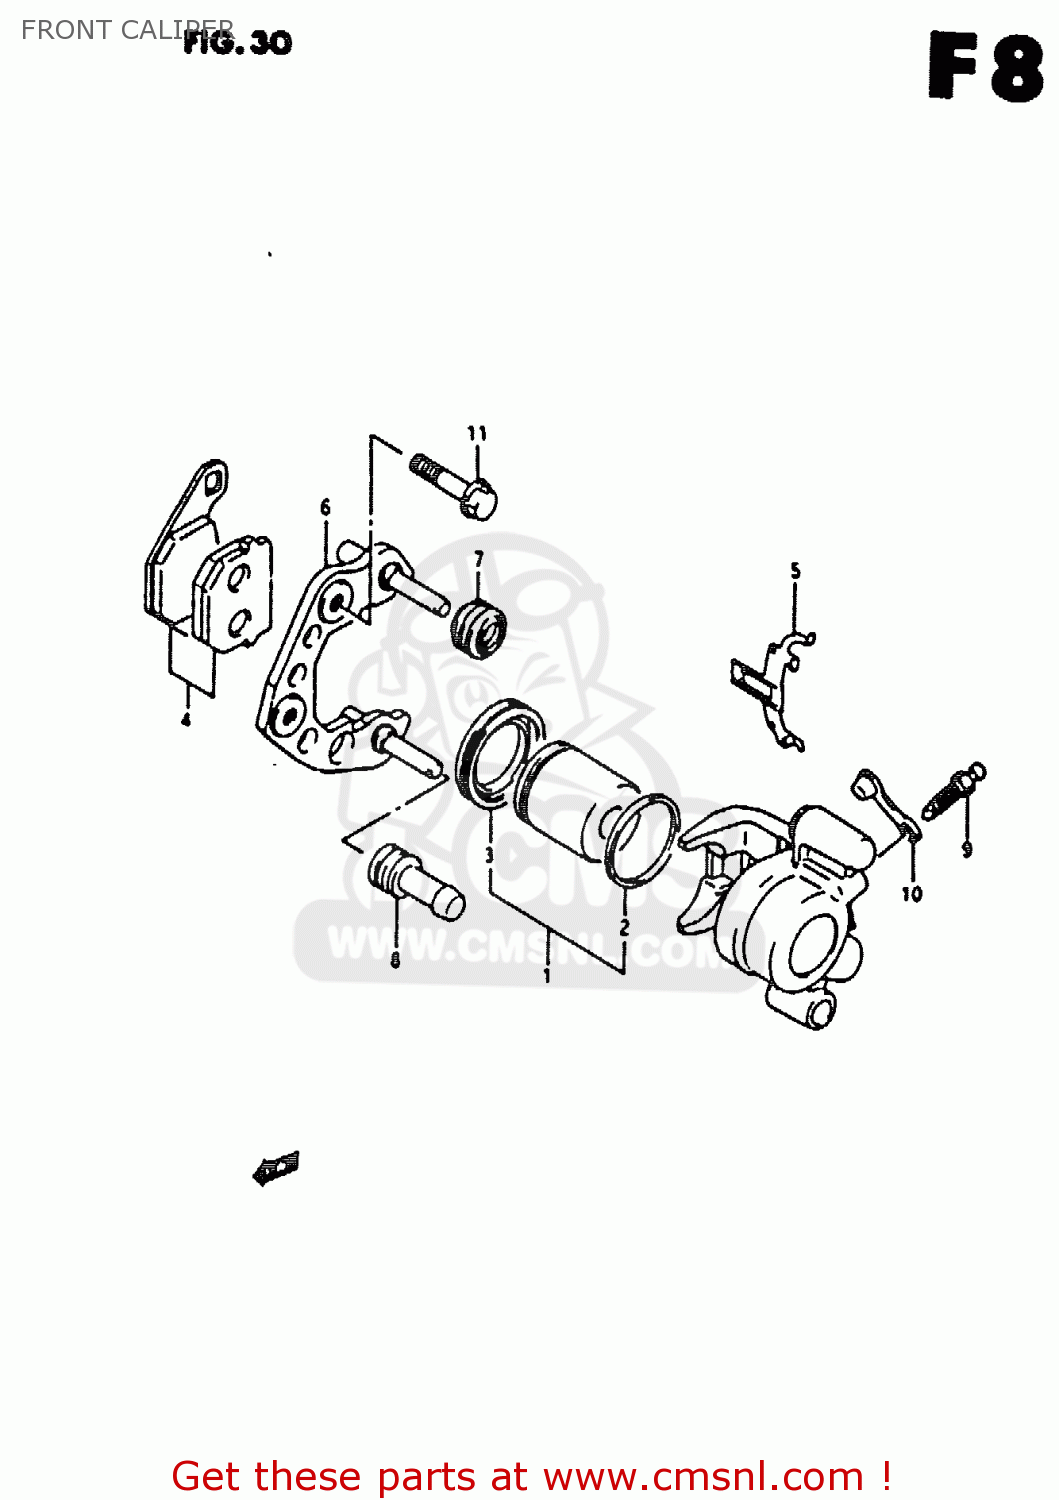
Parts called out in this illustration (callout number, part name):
1	PISTON SET
2	SEAL
3	BOOT
4	PAD SET (NAS)
5	SPRING,PAD
6	CARRIER
7	BOOT,AXLE
8	INSULATOR,AXLE
9	BLEEDER
10	CAP,BLEEDER
11	BOLT(8X35)
